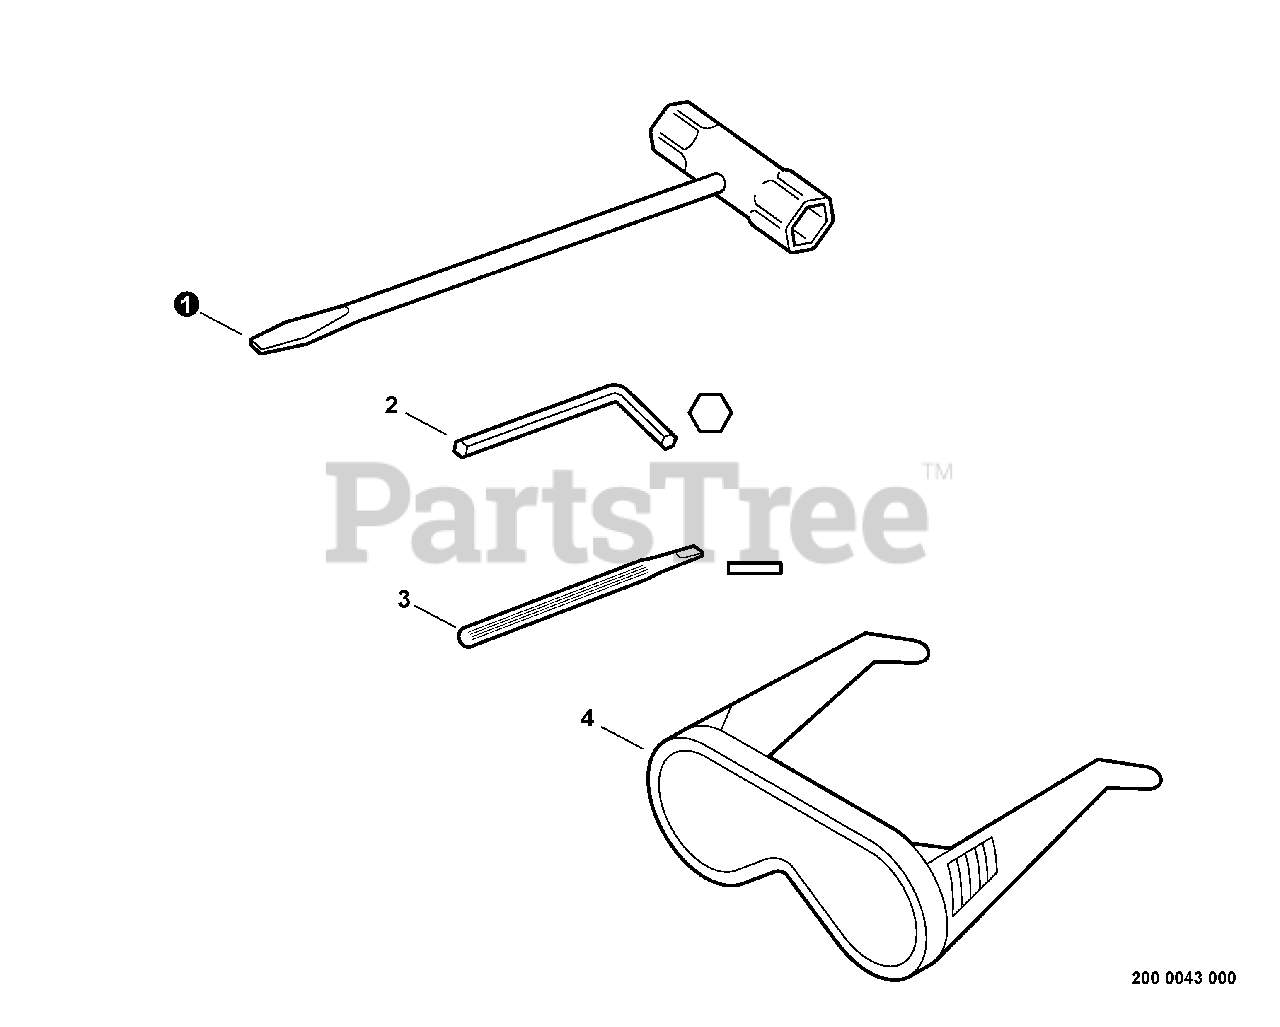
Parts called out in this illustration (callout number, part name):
1	T-WRENCH - 13X19mm
2	HEX KEY - 4mm
3	SCREWDRIVER - PLASTIC
4	GOGGLES
